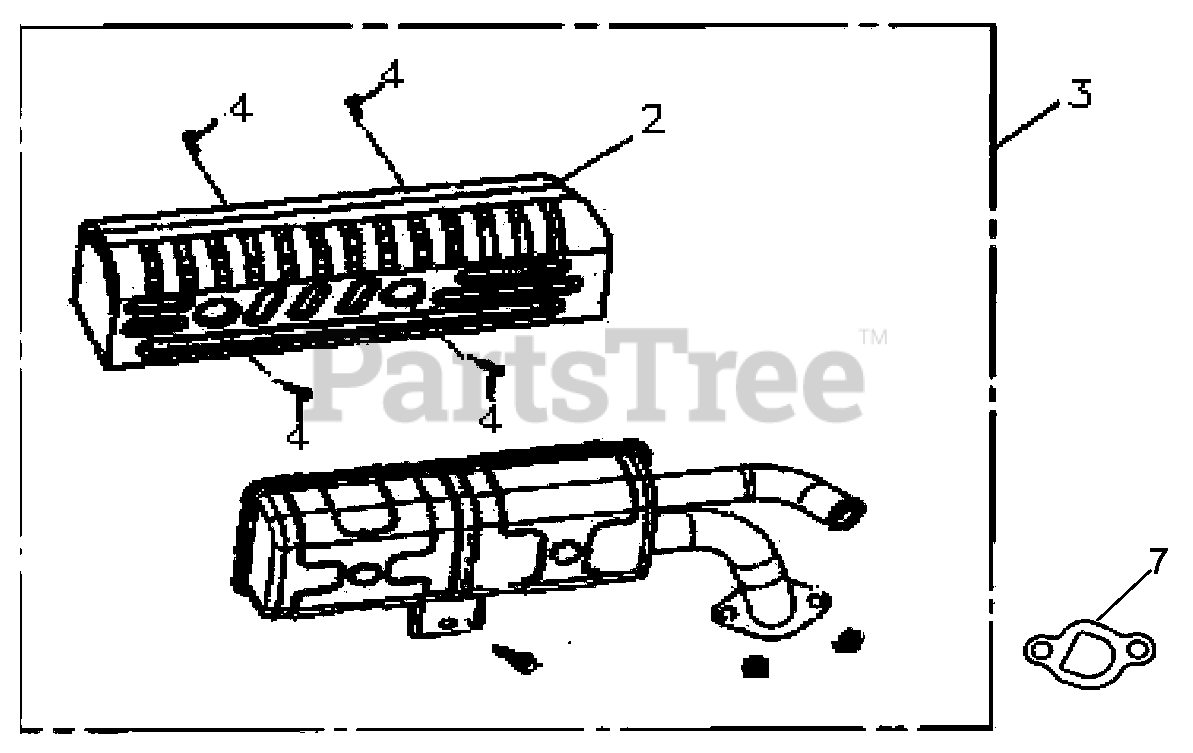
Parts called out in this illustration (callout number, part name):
2	INNER PIPE ASSY., MUFFLER
3	MUFFLER ASSY.
4	BOLT, FLANGE
7	GASKET, EX. PIPE
